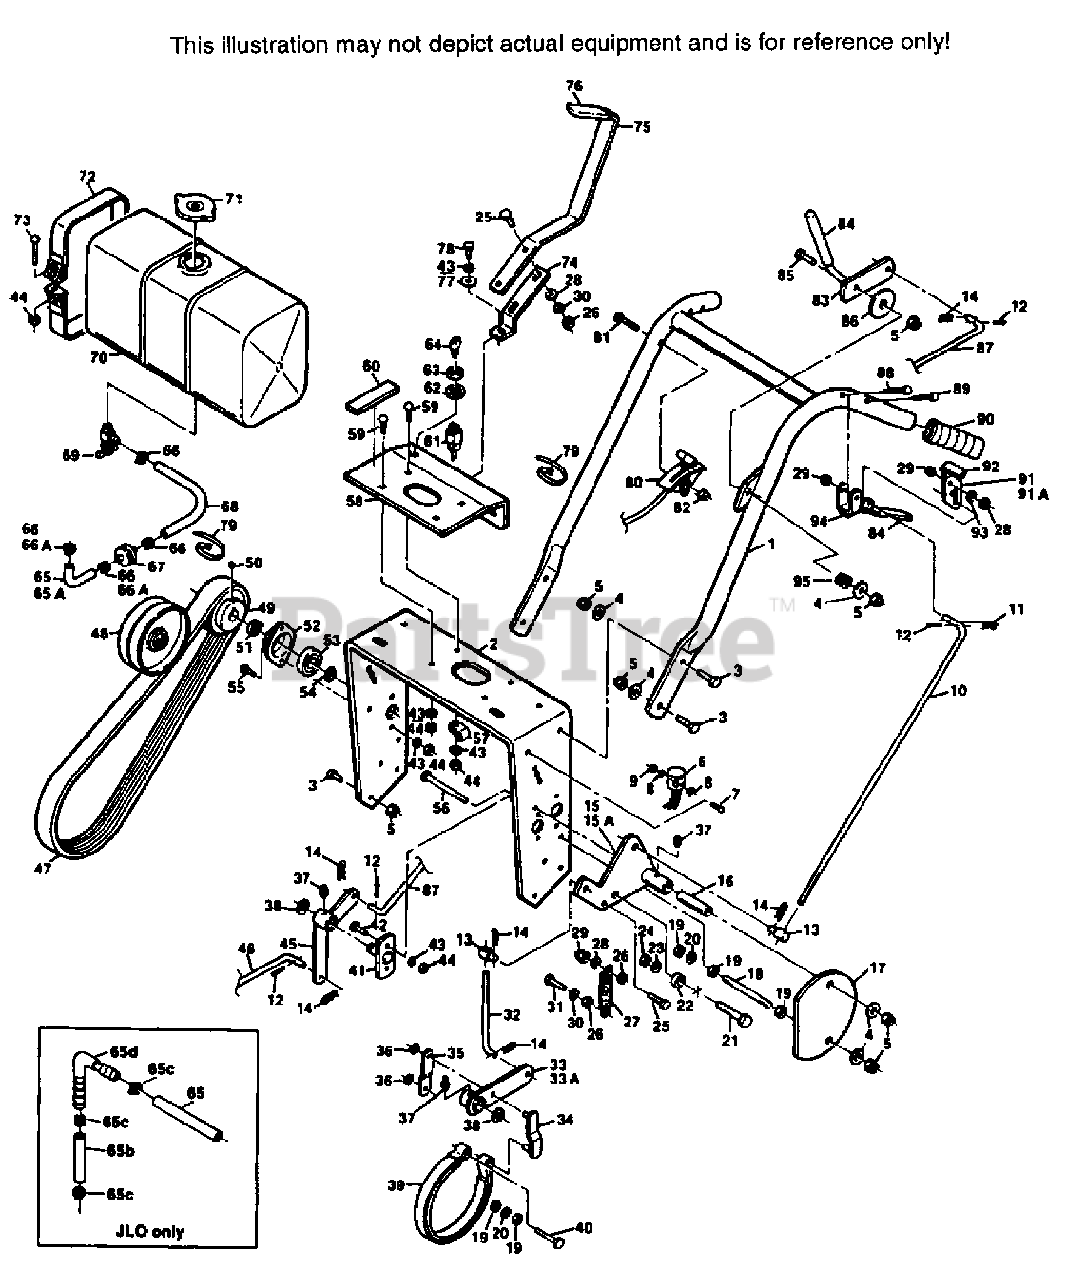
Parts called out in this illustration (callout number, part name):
4	WASHER, 25/64 X 15/16 X 12 GA.
5	HEX NUT, 3/8-16 ELASTIC STOP
6	WIRE HARNESS
8	LOCKWASHER, #10 EXT. TOOTH
10	CONTROL ROD, STEERING
11	HAIR PIN, SMALL
13	SWIVEL JOINT
14	HAIR PIN, LARGE
15	IDLER BRACKET WLD, RH
15A	IDLER BRACKET WLD, LH
16	IDLER SLEEVE
17	BELT GUARD
18	SUPPORT BELT GUARD
24	HEX NUT, 1/2-13 ELASTIC STOP
25A	CARRIAGE 1/4-20 X 1
27	SPRING, IDLER TENSION
28	WASHER, 11/32 X 11/16 X 16 GA.
29	HEX NUT, 5/16-18 ELASTIC STOP
32	BRAKE ROAD
33	BRAKE LEVER WLD, RH
33A	BRAKE LEVER WLD, LH
34	BRAKE LINK WLD.
35	BRAKE LINK
36	NUT, PUSH-ON, 3/8
37	GREASE FITTING, STR., 1/4-28
38	REAINING RING, 5/8 EXT.-"E"
39	BRAKE BAND
41	BELL CRANK PIVOT WLD.
45	BELL CRANK WLD, CLUTCH
46	BLADE CLUTCH ROD, LOWER
47	BELT, WHEEL DRIVE
48	IDLER PULLEY, WHEEL DRIVE
49	PULLEY, JACKSHAFT(INCL. 50)
51	SPACER, JACKSHAFT PULLEY
52	FLANGE, JACKSHAFT BEARING
53	BEARING, JACKSHAFT
54	RETAINING RING, 5/8 EXT.-BASIC
57	CLAMP
58	SHIFTER PLATE
60	RUBBER PAD(LOWER)
61	KEY SWITCH
62	LOCKWASHER, INTERNAL TOOTH, 5/8
63	HEX NUT, 5/8-32
64	KEY, IGNITION
67	FUEL FILTER
68	FUEL HOSE, LONG 1/4 ID X 17"
69	VALVE, FUEL SHUT OFF
70	FUEL TANK ASSY.(INCL. DECALS 23,71,69)
71	FUEL TANK CAP
72	STRAP, FUEL TANK
74	SHIFTER LEVER
75	SHIFT LEVER ASSY.(INCL. 76)
76	GRIP, SHIFT LEVER
77	WASHER, 17/64 X 7/8 X 1/8 HT
78	HEX HEAD BOLT, 1/4-28 X 3/4 GRADE 8
79	CABLE TIE
82	HEX NUT, 1/4-20 ELASTIC STOP
83	BLADE CLUTCH LEVER ASSY.(INCL. 84)
84	GRIP, LEVER
86	WASHER, 3/8 X 2 X 16 GA.
87	BELT CLUTCH ROD, UPPER
90	GRIP, HANDLE
91	NEUTRAL LATCH ASSY, RH(INCL. 92)
91A	NEUTRAL LATCH ASSY, LH(INCL. 92)
92	GRIP, NEUTRAL LATCH
93	CURVED SPRING WASHER
94	BRAKE LEVER ASSY.(INCL. 84)
95	SPRING COMPRESSION
